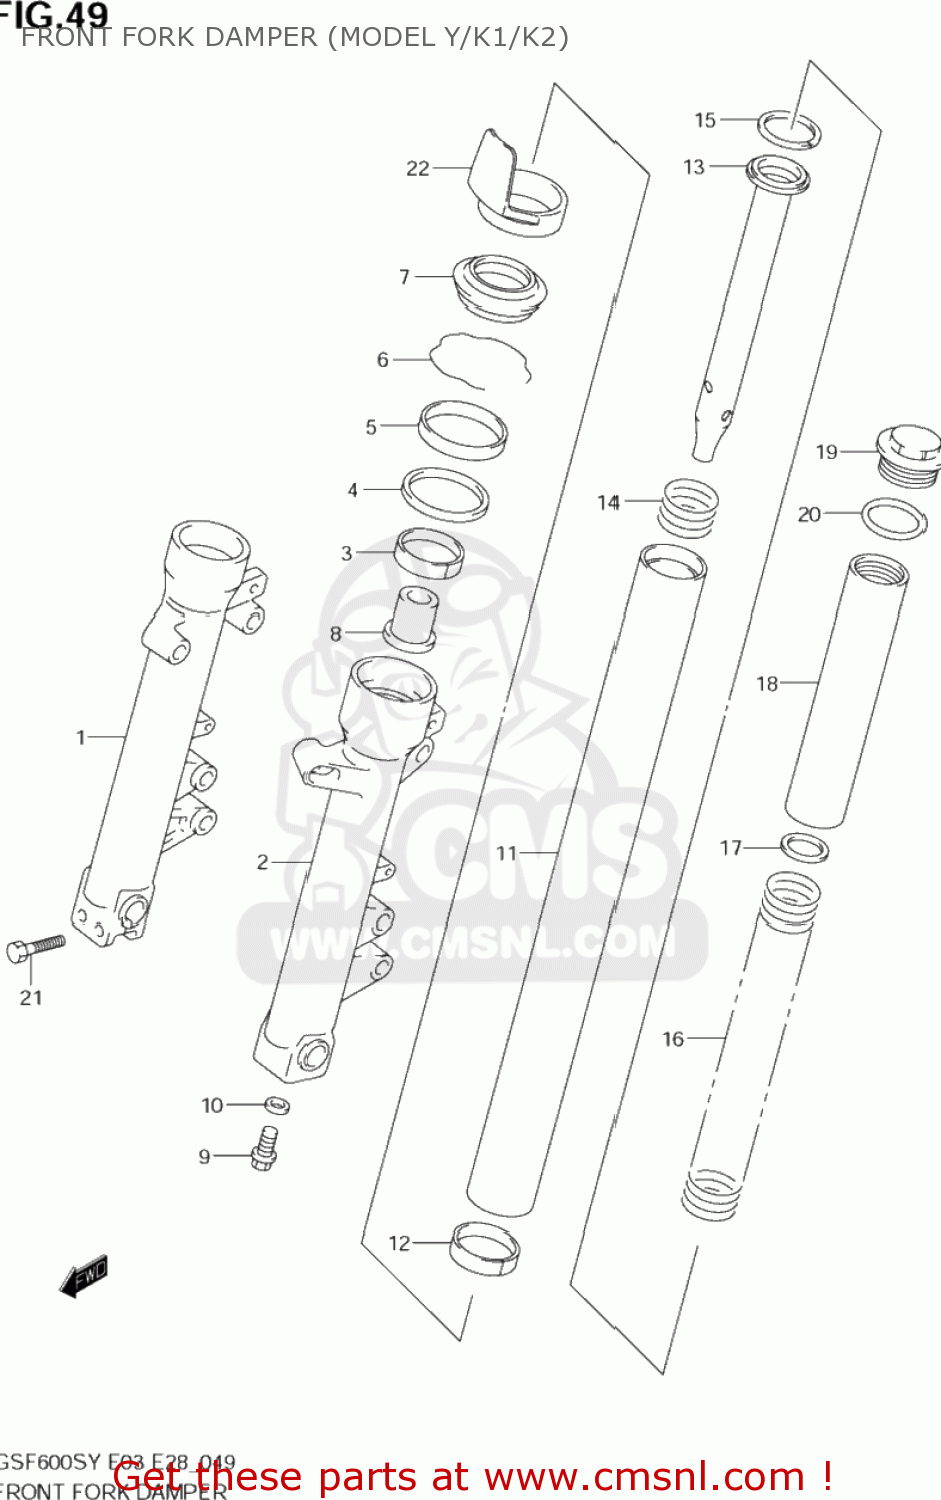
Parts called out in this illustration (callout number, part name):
1	TUBE,OUTER,R
2	TUBE,OUTER,L
3	METAL,SLIDE
4	WASHER,FORK OIL SEAL
5	SEAL,OIL
6	RING,OIL SEAL STOPPER
7	SEAL,DUST
8	PIECE,OIL LOCK
9	BOLT,FORK CYLINDER(10X25)
10	GASKET (NAS)
11	TUBE,INNER
12	PISTON
13	CYLINDER
14	SPRING,REBOUND
15	RING,PISTON
16	SPRING,FR
17	WASHER(22.5X35.9X1.6)
18	SPACER,SPRING
19	CAP,FORK
20	O RING(D:3.5,ID:31.7)
21	BOLT
22	PROTECTOR
